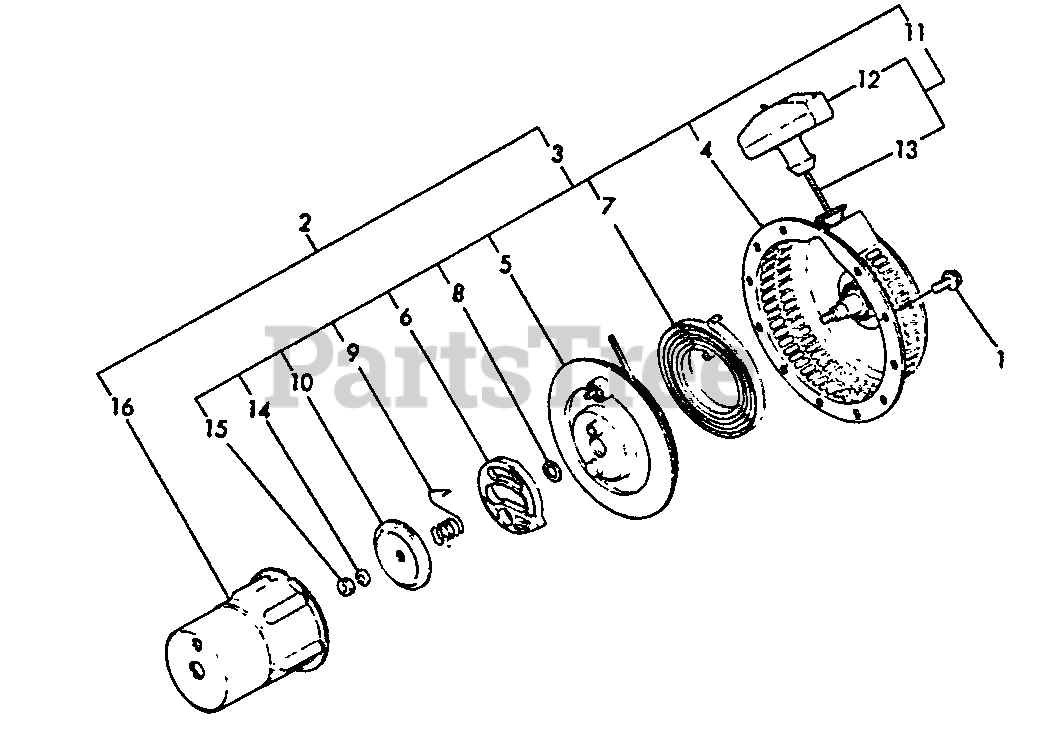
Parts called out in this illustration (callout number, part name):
1	BOLT - 6×8 -- PLATED
2	STARTER ASSY
3	STARTER ASSY, RECOIL
4	CASE, STARTER
5	REEL
7	SPRING, SPIRAL
8	WASHER
9	SPRING, FRICTION
10	PLATE, FRICTION
11	STARTER ROPE ASSY
12	GRIP, STARTER
13	ROPE, STARTER
14	LOCKWASHER - 6
15	NUT - 6
16	PULLEY, STARTER
